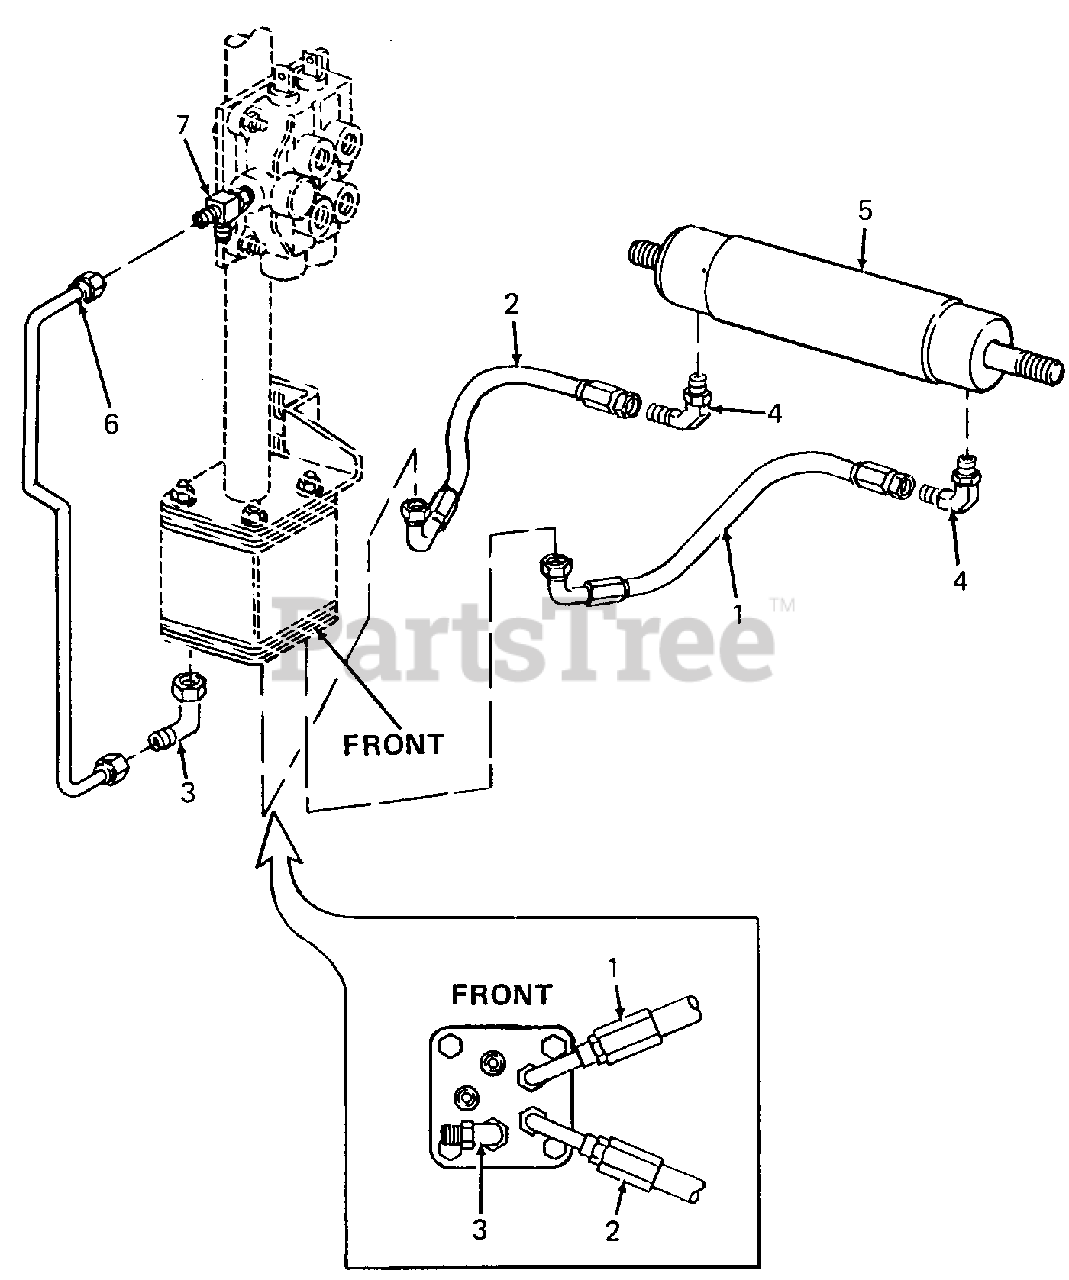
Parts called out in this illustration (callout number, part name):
1	Hose, Steering, 10.5 Lg
2	Hose, Steering, 8.9 Lg
3	Fitting, 90 Deg
4	Elbow, 90 Deg Tube
5	Cylinder, Power Steering
6	Tube Assy, Valve Pressure
7	T-Fitting
